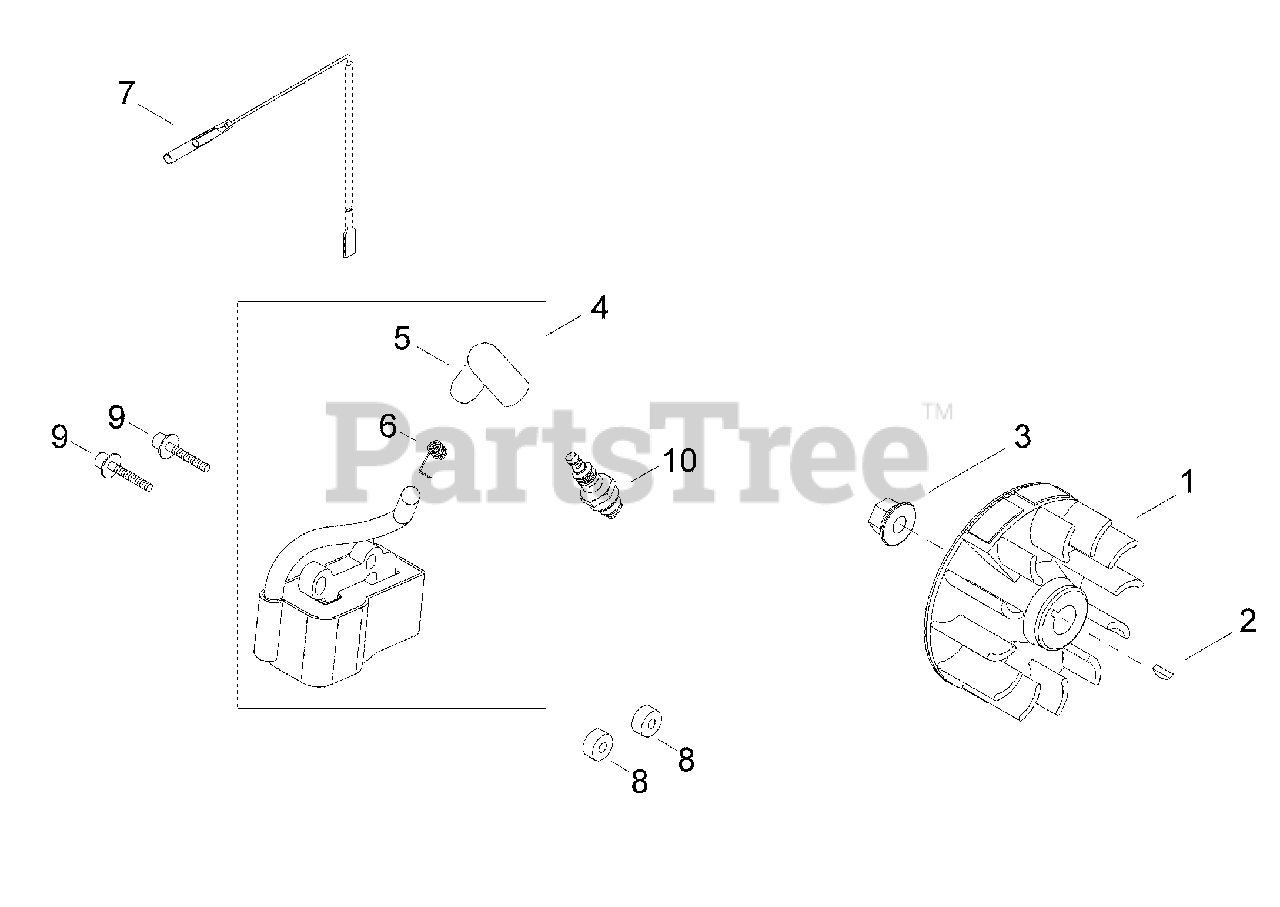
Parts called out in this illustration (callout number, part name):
1	FLYWHEEL
2	KEY, WOODRUFF 3×10
3	NUT M8
4	COIL ASSY, IGNITION
5	CAP, SPARK PLUG
6	TERMINAL, SPARK PLUG
7	LEAD - IGNITION L= 220 MM
8	INSULATOR 4.2×11×6
9	BOLT M4×26
10	SPARK PLUG - CMR5H
